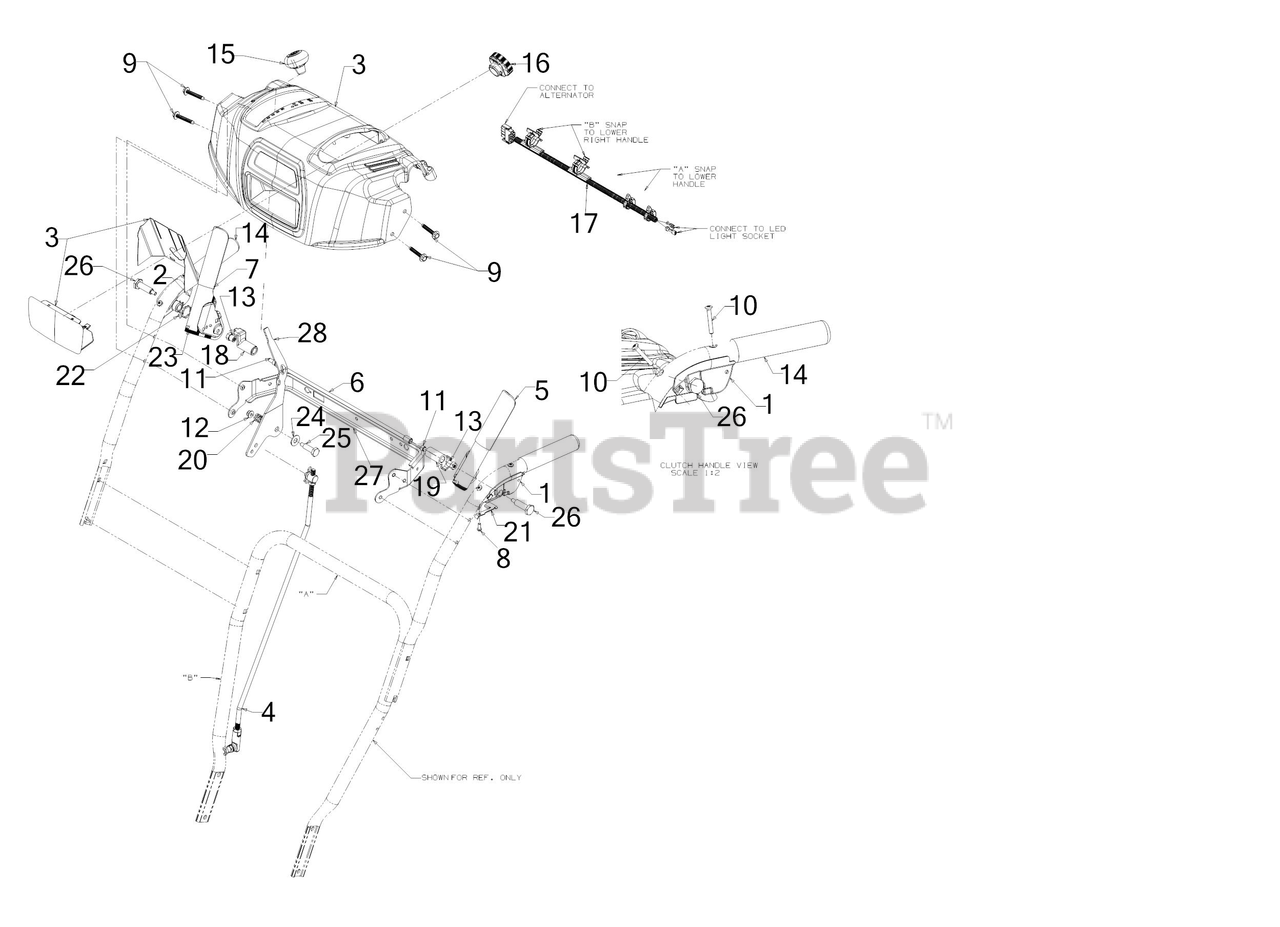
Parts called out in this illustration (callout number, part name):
1	CLUTCH LOCK HANDLE ASSEMBLY (LH)
2	CLUTCH LOCK HANDLE ASSEMBLY (RH)
3	HANDLE PANEL ASSEMBLY (CRAFTSMAN)
4	SHIFT ROD ASSEMBLY
5	HANDLE ASSEMBLY (LH)
6	PIVOT ROD
7	HANDLE ASSEMBLY (RH)
8	SCREW #8-16 x .50
9	SCREW 1/4-20 x 1.625
10	SCREW #10-24 x 1.375
11	SCREW 1/4-20 x .50
12	FLANGE LOCK NUT
13	HEX NUT W/PATCH
15	SHIFT KNOB
16	HEADLIGHT ASSEMBLY
17	LIGHT HARNESS
18	LOCK PLATE
19	CLUTCH LOCK CAM
20	COMPRESSION SPRING
21	CLUTCH SPRING
22	TORSION SPRING
23	RUBBER BUMPER
24	FLAT WASHER
25	SHOULDER SCREW
26	SHOULDER SCREW .437 x 1.345 1/4-20
27	HANDLE SUPPORT BRACKET
28	SHIFT LEVER
